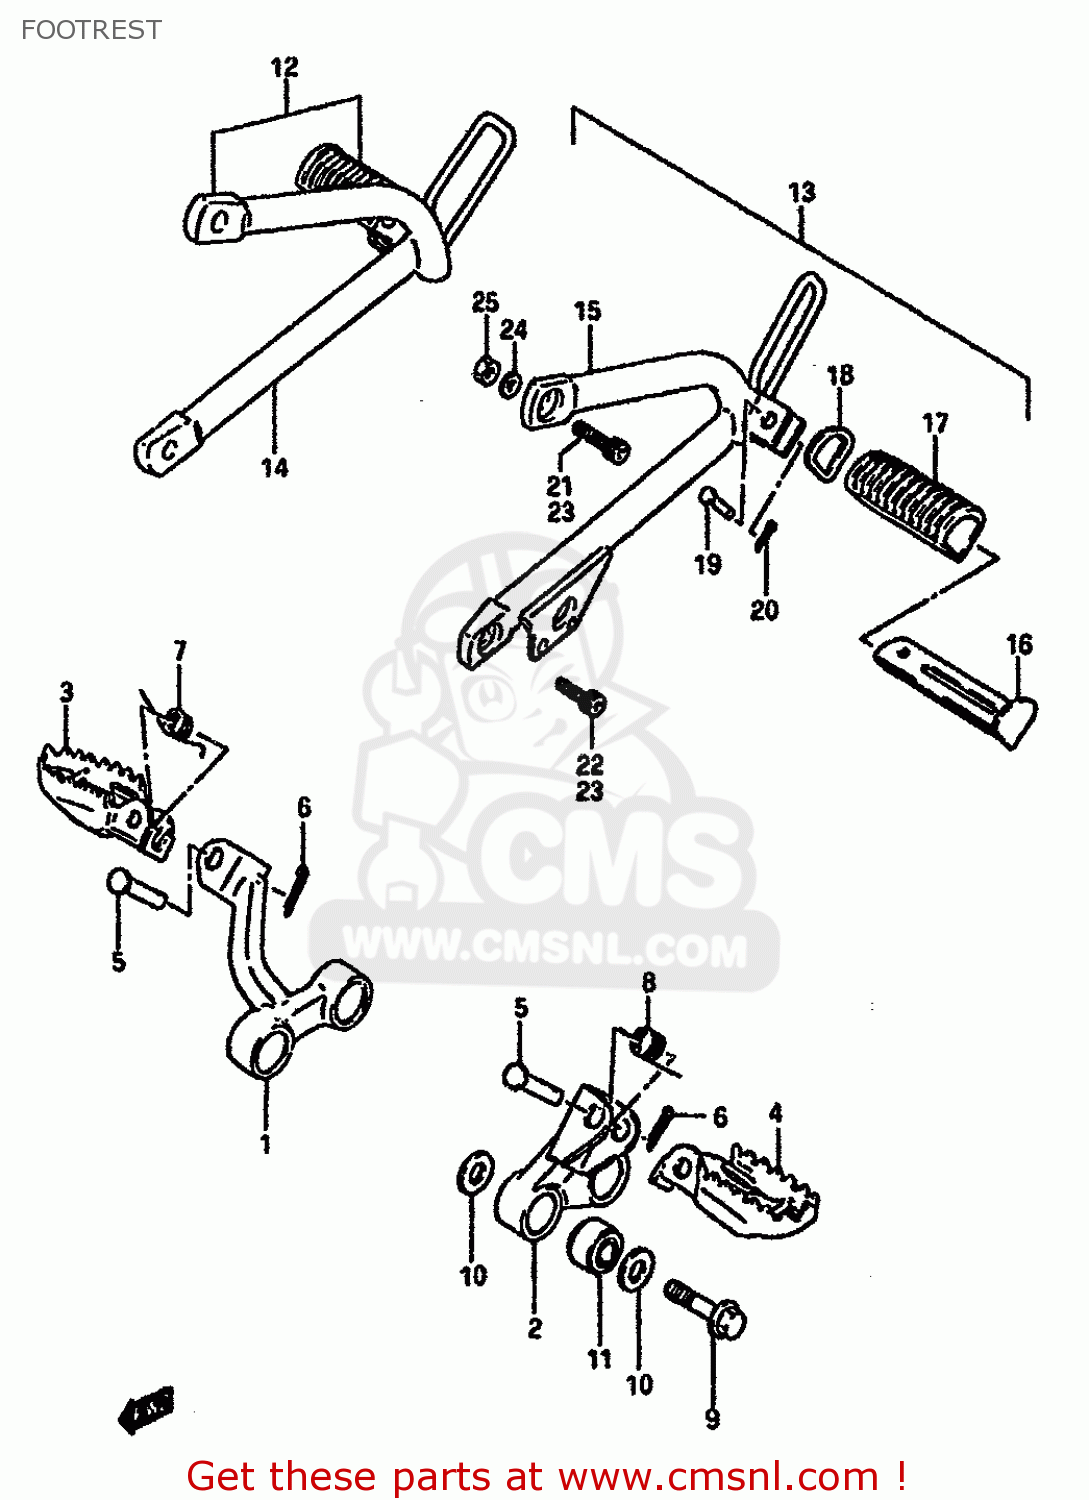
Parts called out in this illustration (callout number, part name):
1	BAR, FOOTREST RH (BLUE)
2	BAR, FOOTREST LH (BLUE)
3	FOOTREST, FRONT RH (BLUE)
4	FOOTREST, FRONT LH (BLUE)
5	PIN
6	PIN 20X20
7	SPRING
8	SPRING
9	BOLT(10X50)
10	WASHER
11	BUSH(10.2X25X19)
12	FOOTREST, PILLION RH (BLUE)
13	FOOTREST, PILLION LH (BLUE)
14	HOLDER, RH (BLUE)
15	HOLDER, LH (BLUE)
16	BAR COMP,PILLION FOOTREST
17	RUBBER,PILLION FOOTREST
18	WASHER,PILLION FOOTREST
19	PIN
20	PIN
21	BOLT
22	BOLT
23	BOLT
24	WASHER,LOCK,8.
25	NUT
